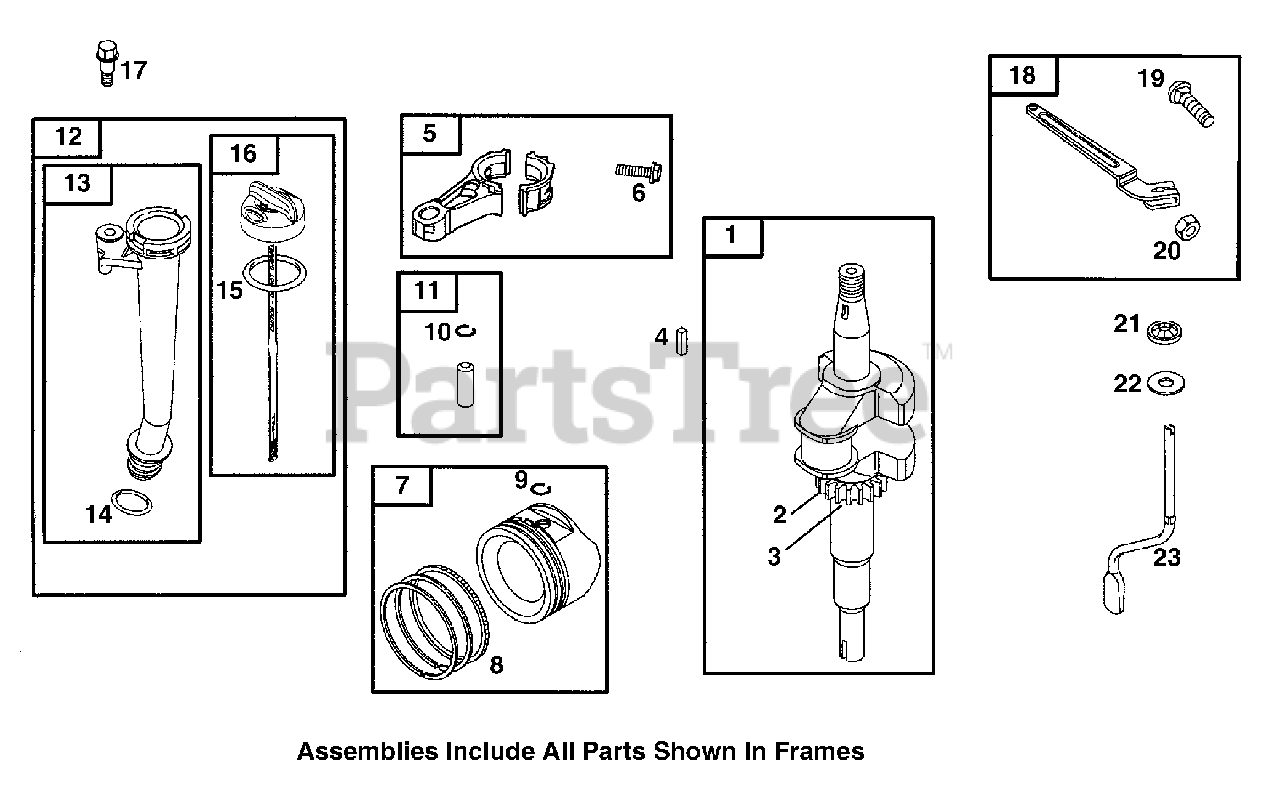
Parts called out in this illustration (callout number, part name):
1	Crankshaft
2	Timing Gear
3	Timing Key
4	Flywheel Key
5	Connecting Rod
6	Connecting Rod Screw
7	Piston Assembly (Standard)
8	Ring Set (Standard)
9	Piston Pin Lock
10	Piston Pin Lock
11	Piston Pin (Standard)
12	Dipstick/Tube Assembly
13	Oil Fill Tube
14	Seal-O-Ring
15	Seal-O-Ring
17	Shoulder Screw
18	Governor Lever
19	Governor Lever Bolt
21	Governor Shaft Retainer
22	Flat Washer
23	Governor Crank
